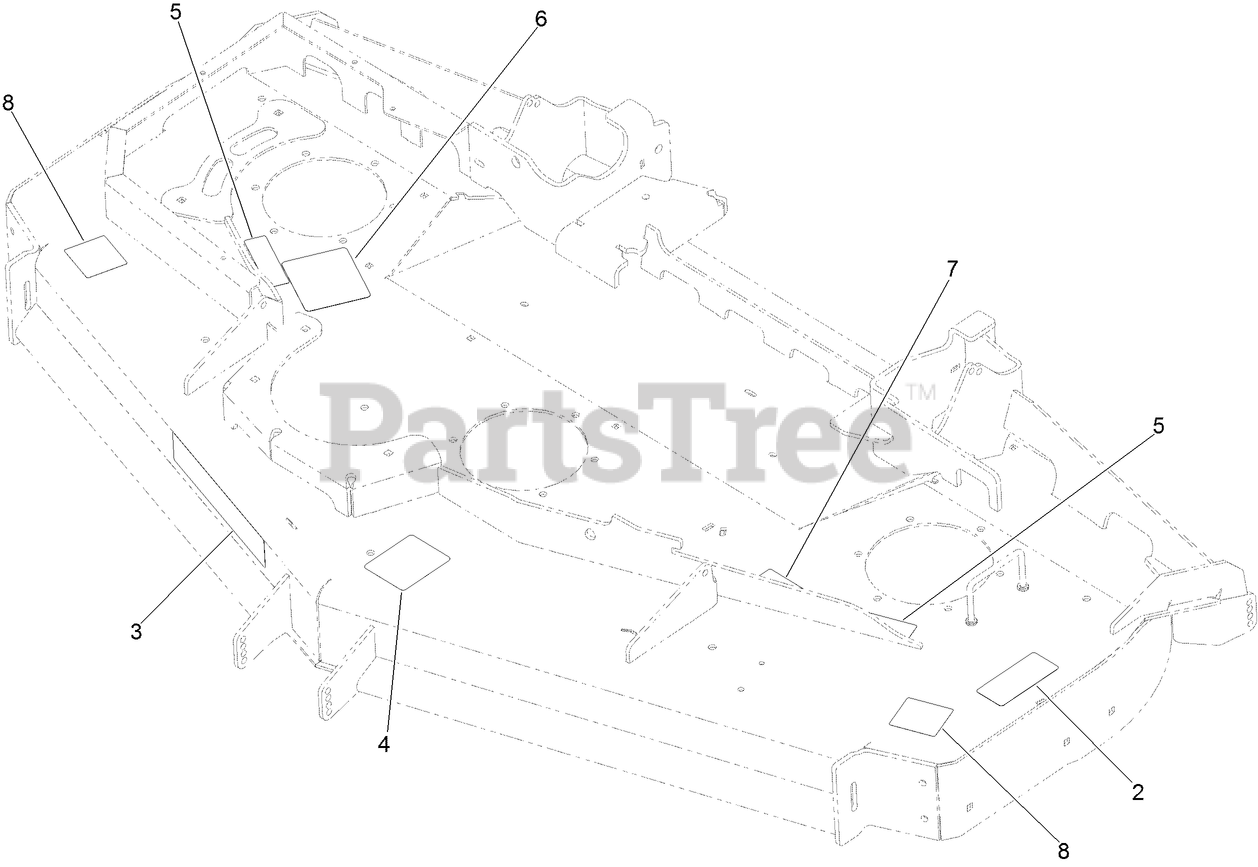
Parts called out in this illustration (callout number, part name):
2	DECAL-TORQUE, BLADE BOLT
4	DECAL-ROLLER, ANTI-SCALP
5	DECAL-COVER, MISSING
6	DECAL-SPINDLE, COUNTER ROTATING
7	DECAL-BELT ROUTING REAR
8	DECAL-DANGER, THROWN OBJECT
